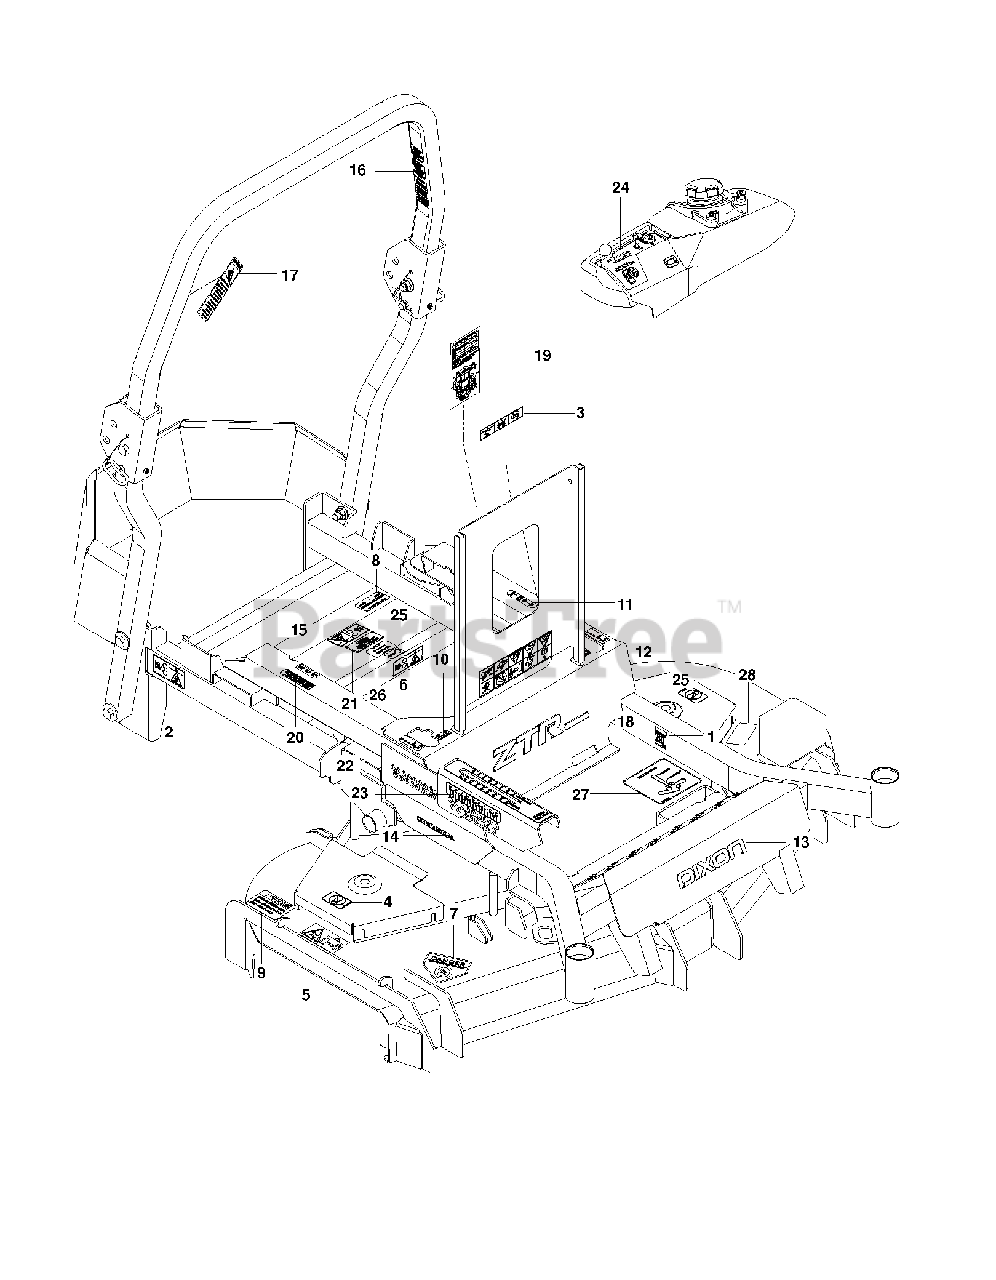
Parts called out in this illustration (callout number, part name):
2	DECAL, BELT DRIVE
4	DECAL, NO STEP
5	DECAL, EURO SEVERING
6	DECAL, MOTION CONTROL
7	DECAL, CPSC
8	DECAL, FUEL
9	DECAL, CAUTION
10	DECAL, TRACKING
11	DECAL, PARK BRAKE
12	DECAL, WARNING
14	DECAL, COMMERCIAL
16	DECAL, ROPS
17	DECAL, ROPS, WARNING
18	DECAL, DX200
19	DECAL, SERVICE
20	DECAL, WARNING SPARK ARRESTOR
22	DECAL, HEIGHT
23	DECAL, HEIGHT
25	DECAL, ECM, AUSTRALIA
26	DECAL, OIL TANK
27	DECAL, BELT ROUTING
